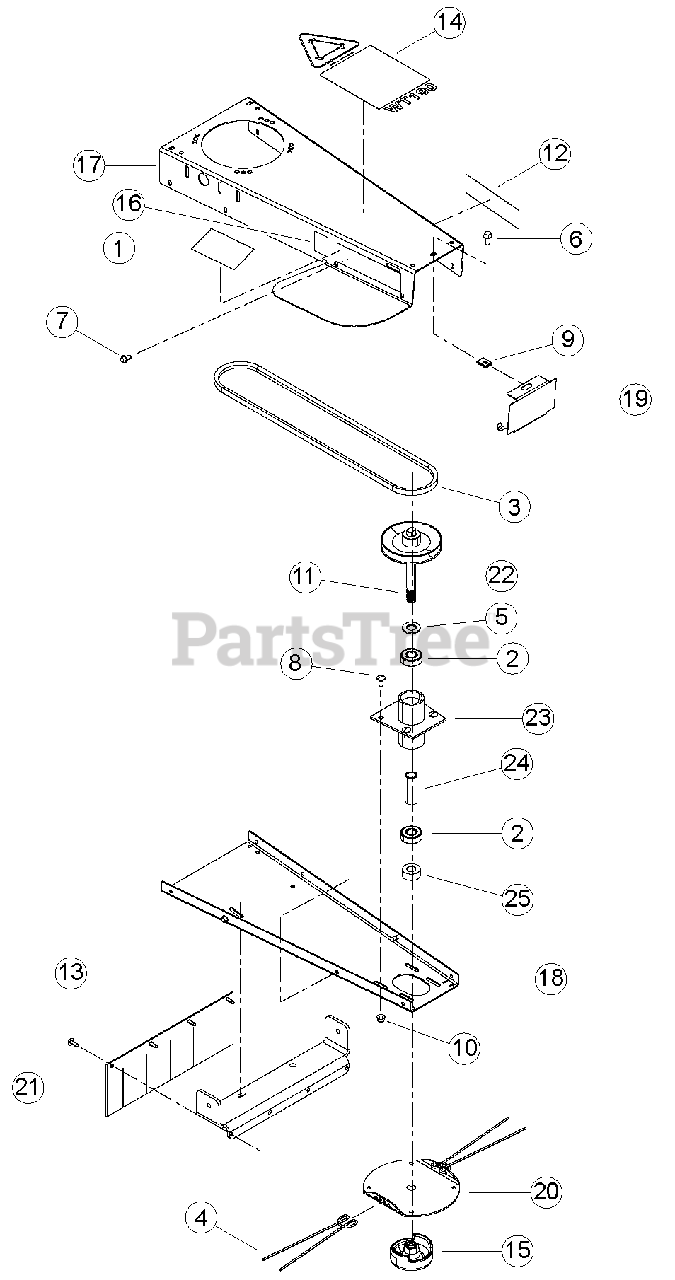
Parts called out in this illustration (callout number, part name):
1	DECAL, GRINDER DANGER
2	BEARING, 3/4 BALL
3	BELT, 4L 53 ARAMID
4	STRING, .155 X 20-1/2
5	WASHER, 3/4 SAE FLAT ZP, 21PC/LB
6	BOLT, 5/16 X 3/4 FLANGE NC
7	SCREW, 11/32 X 7/8 HWH AB THREAD ZP
8	BOLT, 5/16X3/4 GR5 NC ZP CRG
9	NUT 5/16-18 TINNERMAN U-TYPE
10	NUT, 5/16-18 NYLOCK FLANGE
11	ANTI-SEIZE LUBRICANT 8 OZ BRUSH TOP BTL (APPLIED TO SPINDLE THREADS ON TRIMMER PULLEY)
12	DECAL, ECHO BEARCAT 6.82 X 1.90
13	RIVET, PLASTIC 1/4 X 7/8
14	DECAL, WT190 INFORMATION
15	MOWBALL, CAST TRIMMER
16	DECAL, ECHO BEARCAT QR CODE
17	BODY, TRIMMER STANDOFF
18	BOTTOM, TRIMMER STANDOFF
19	COVER, TRIMMER STANDOFF
20	DISK, TRIMMER HEAD
21	FLAP, TRIMMER
22	WELDMENT, TRIMMER PULLEY
23	WELDMENT, SPINDLE HUB
24	SPACER, TRIMMER SPINDLE
25	SPACER, TRIMMER HEAD
